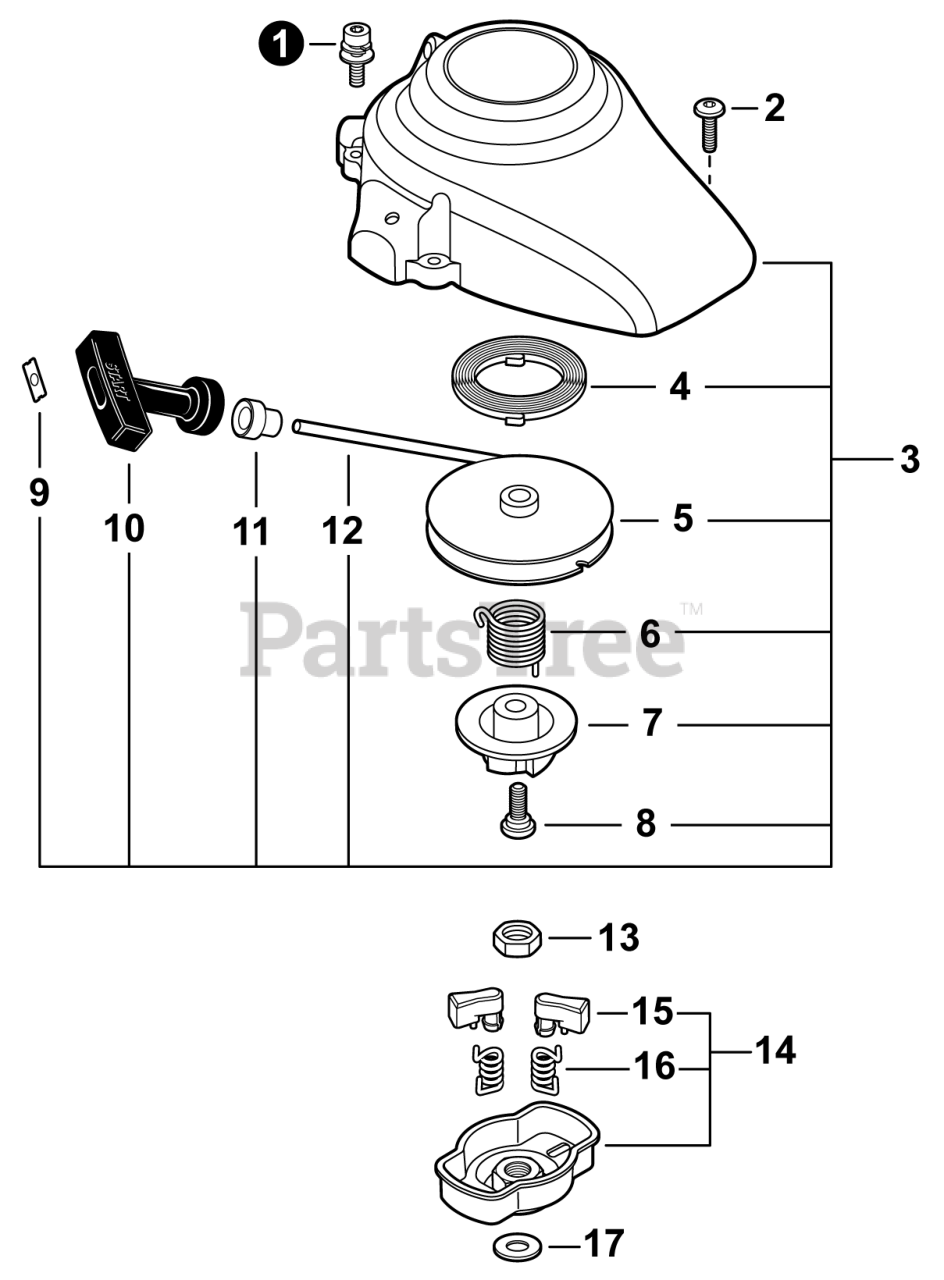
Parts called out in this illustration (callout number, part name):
1	BOLT 4x16
2	BOLT 4x12
3	STARTER ASSY, RECOIL
4	SPRING, RECOIL
5	REEL, ROPE
6	SPRING, COMPRESSION
7	PAWL CATCHER
8	SCREW 5
9	RETAINER, ROPE
10	GRIP, STARTER
11	GUIDE, ROPE
12	ROPE, STARTER 3x700
14	PAWL ASSY, STARTER
15	PAWL, STARTER
16	SPRING, RETURN
17	WASHER 8.5x16x1.2
